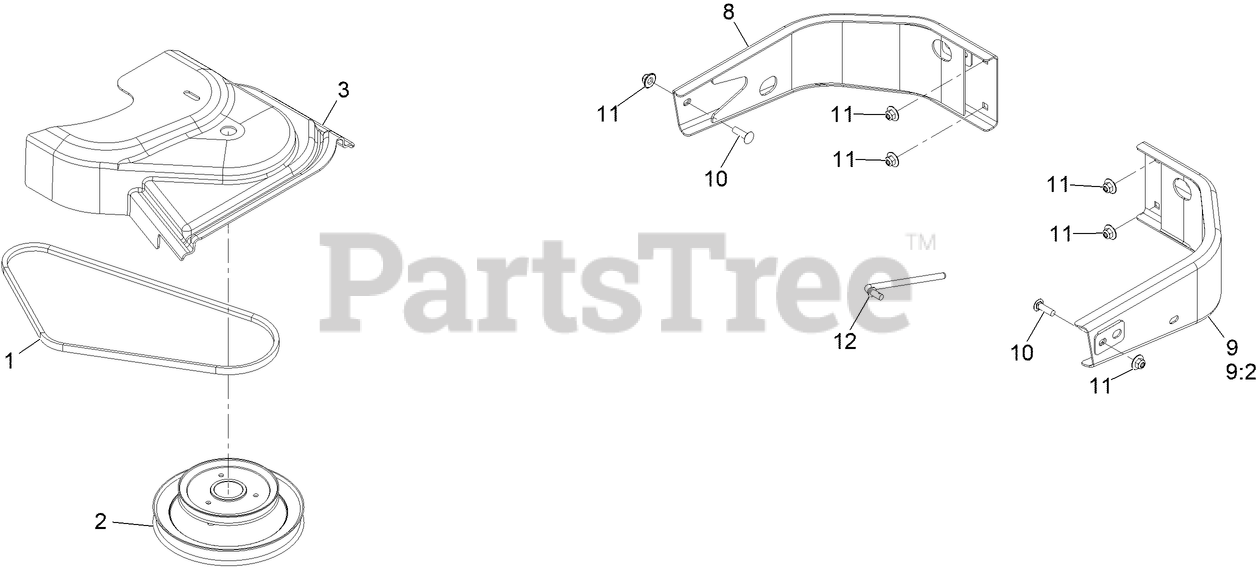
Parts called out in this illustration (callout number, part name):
2	JACKSHAFT,UV DRIVE 724 SPLINED
3	COVER,BELT UV 72
8	BUMPER-RH
9	LH BUMPER ASM
9:2	DECAL-WARNING
10	Bolt-Carriage 3/8-16 X 1 1/4
11	Nut-Nyloc 3/8-16 Flg
12	LINK-HANDLE
